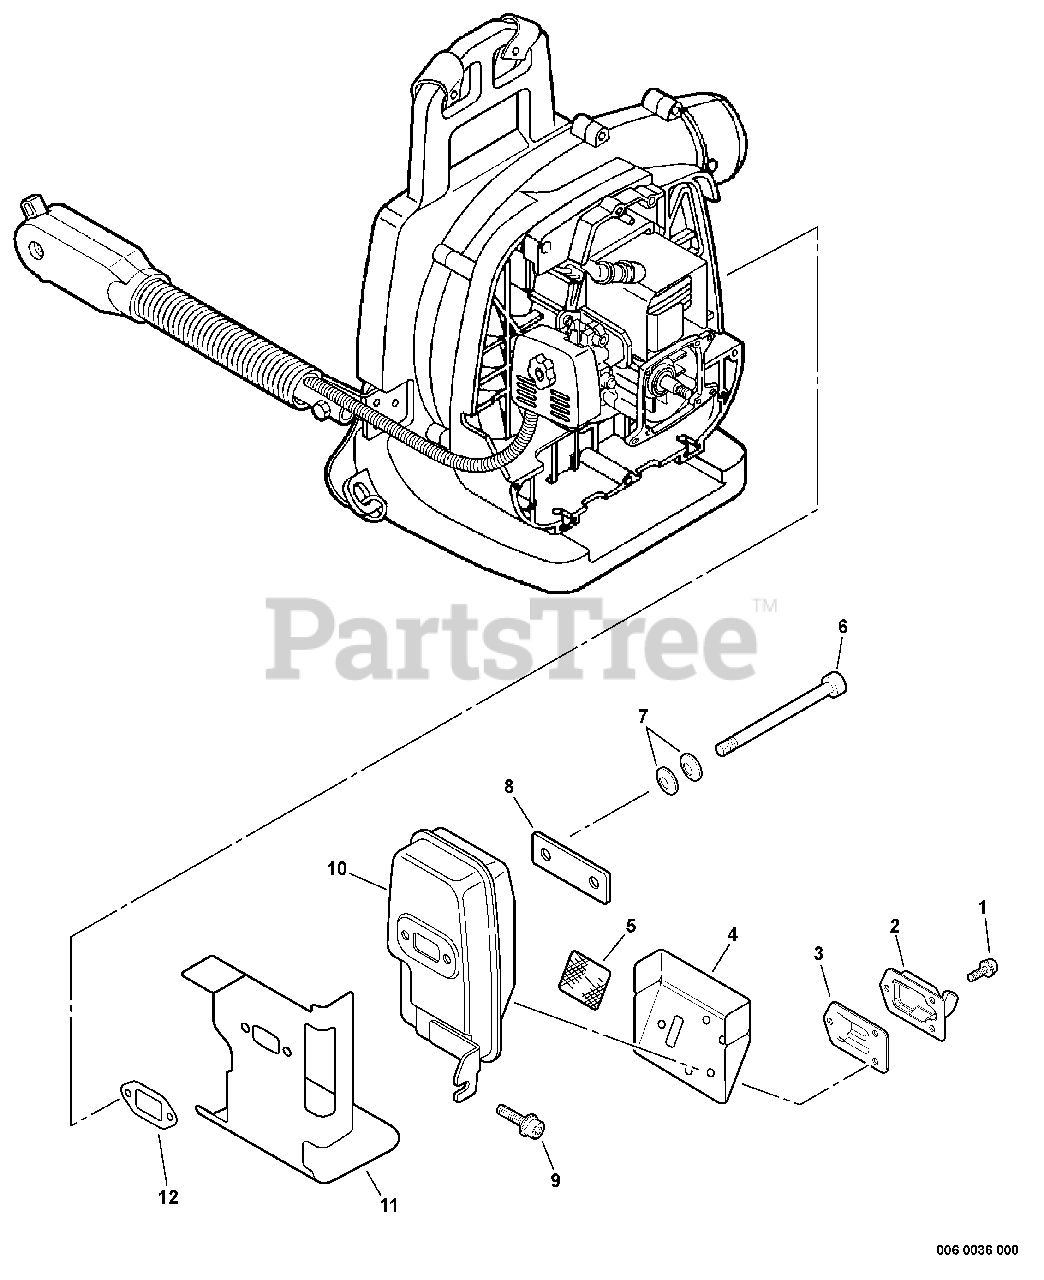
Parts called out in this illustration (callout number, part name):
1	SCREW - 4X12
2	GUIDE, EXHAUST
3	GUIDE, EXHAUST - INNER
4	GASKET, EXHAUST
5	SCREEN, SPARK ARRESTOR
6	BOLT - 5X65
7	WASHER - CONICAL
9	SCREW - 5X16
10	MUFFLER
11	SHIELD, EXHAUST
12	GASKET, EXHAUST
